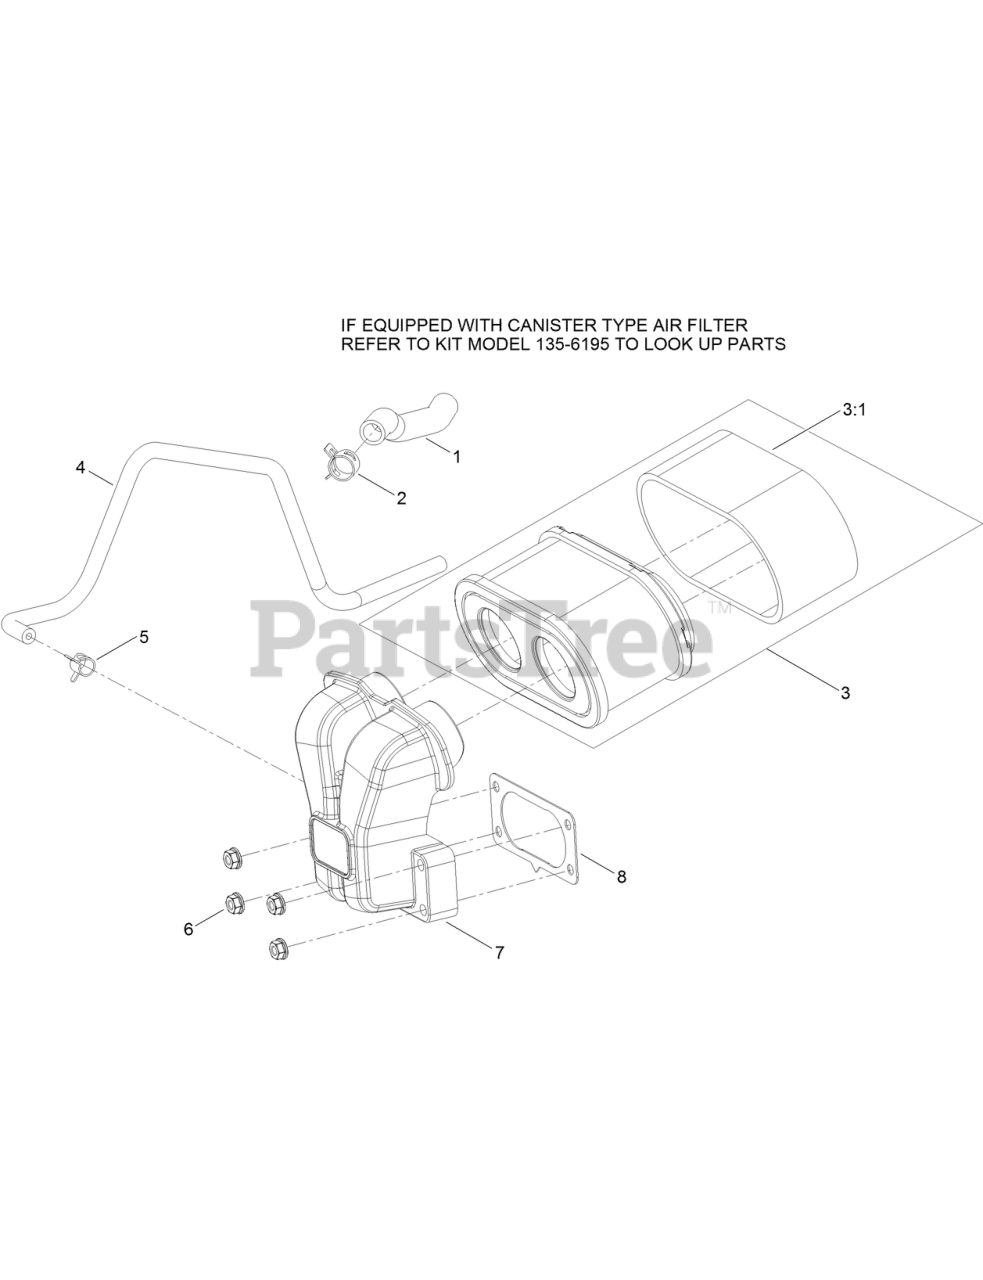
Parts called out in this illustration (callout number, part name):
1	TUBE-BREATHER
2	CLAMP-HOSE
3	AIR FILTER KIT
3:1	PREFILTER
4	HOSE-FUEL
5	CLAMP-HOSE
6	NUT-FLANGE
7	MANIFOLD-FILTER, AIR
8	GASKET-CARBURETOR
